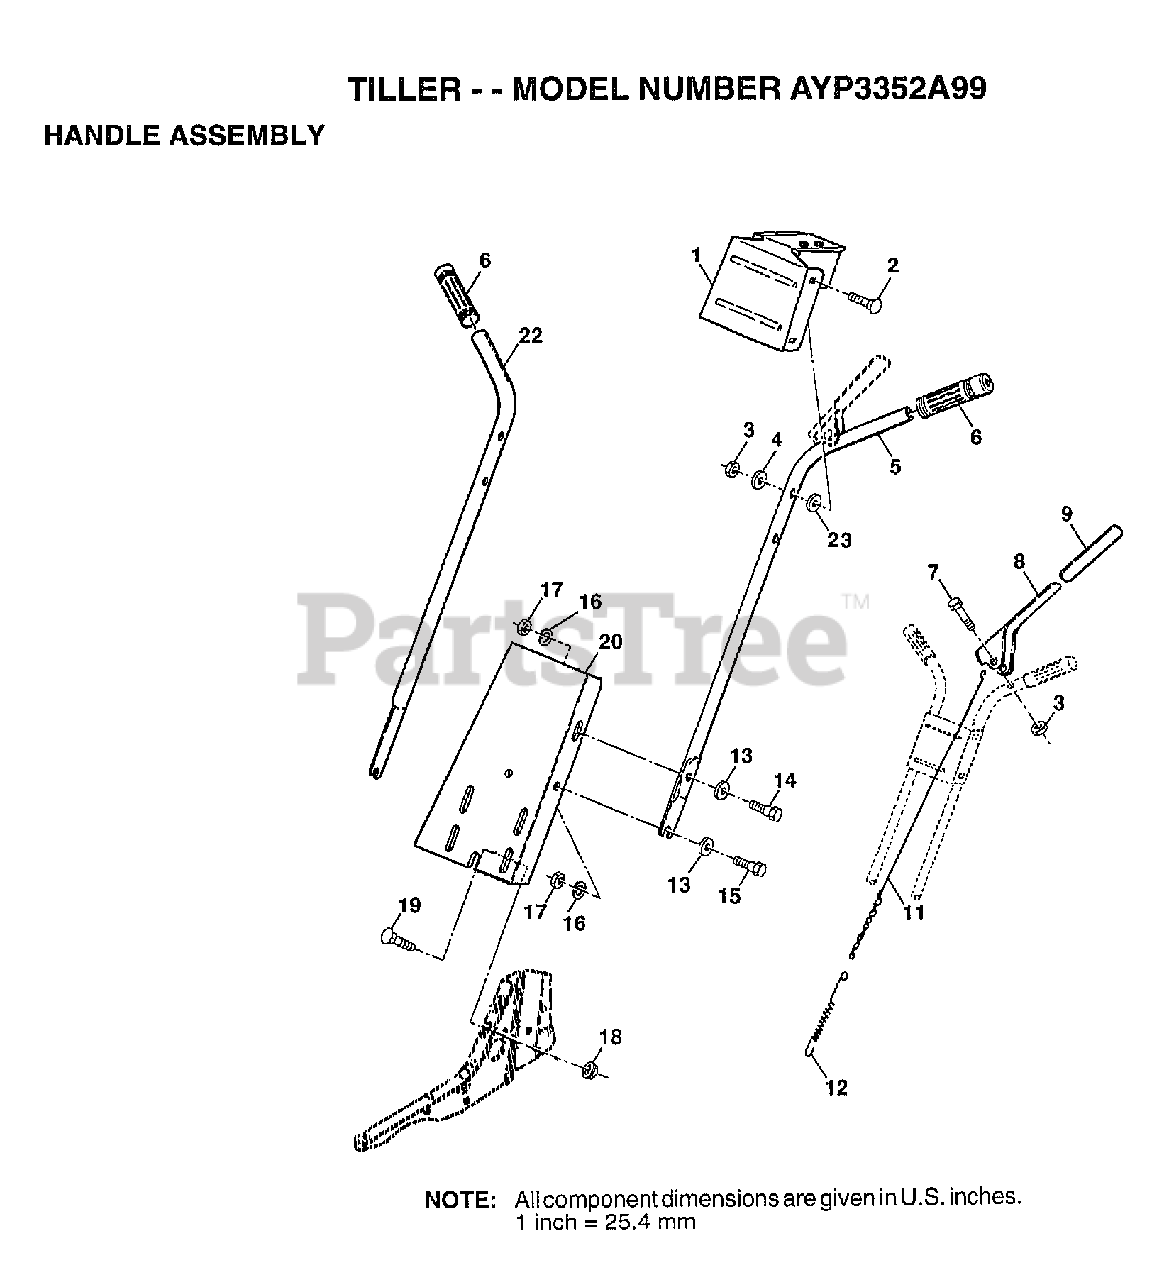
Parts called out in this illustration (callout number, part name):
1	HANDLE BRKT
2	BOLT
4	WASHER
5	HANDLE LH
7	BOLT.HEX.5/16-1.5
8	LEVER.CONTROL.TINE
9	GRIP T
12	SPRING EXT TI
13	WASHER
15	BOLT
16	LOCKWASHER
17	NUT.HEX.5/16-18
18	NUT
19	BOLT
20	PANEL. HANDLE
22	HANDLE RH
23	WASHER
